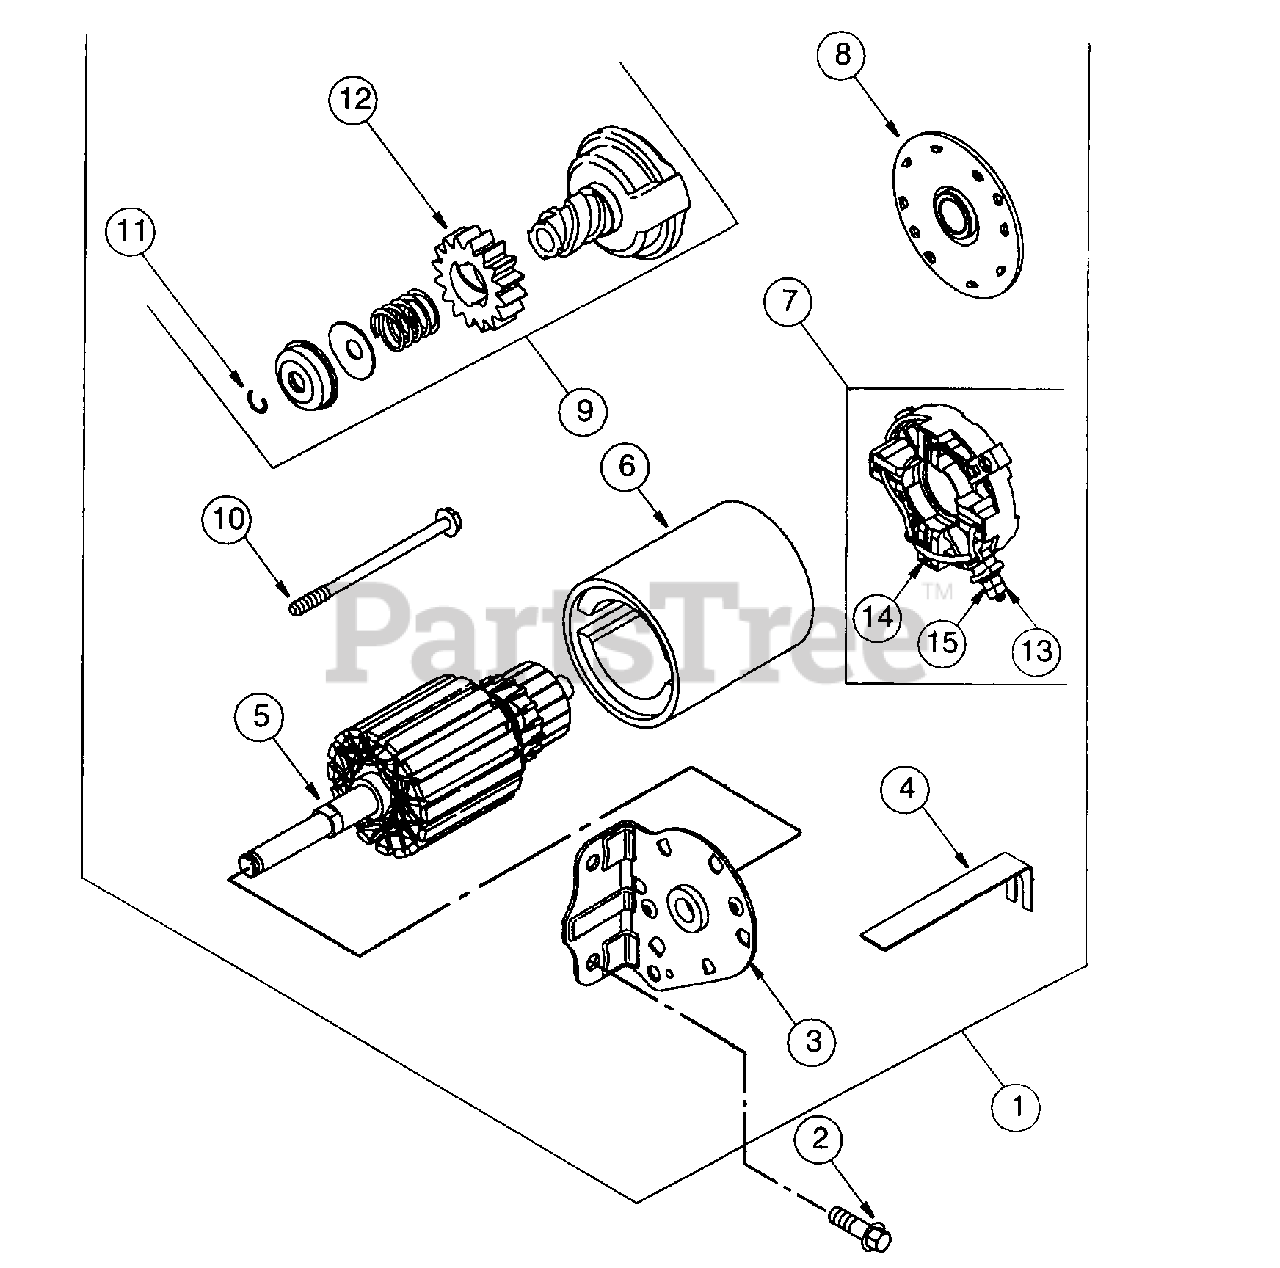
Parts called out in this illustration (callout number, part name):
1	Starter Motor Assembly
2	Screw, Hex
3	Drive End Cap Assembly
4	Strap, Starter
5	Armature Assembly
6	Housing Assembly
7	Retainer, Brush
8	End Cap Assembly, Commutator
9	Starter Drive Group
10	Screw, Hex
11	Ring, Retaining
12	Gear, Starter
13	Nut, Hex
15	Washer, Flat
